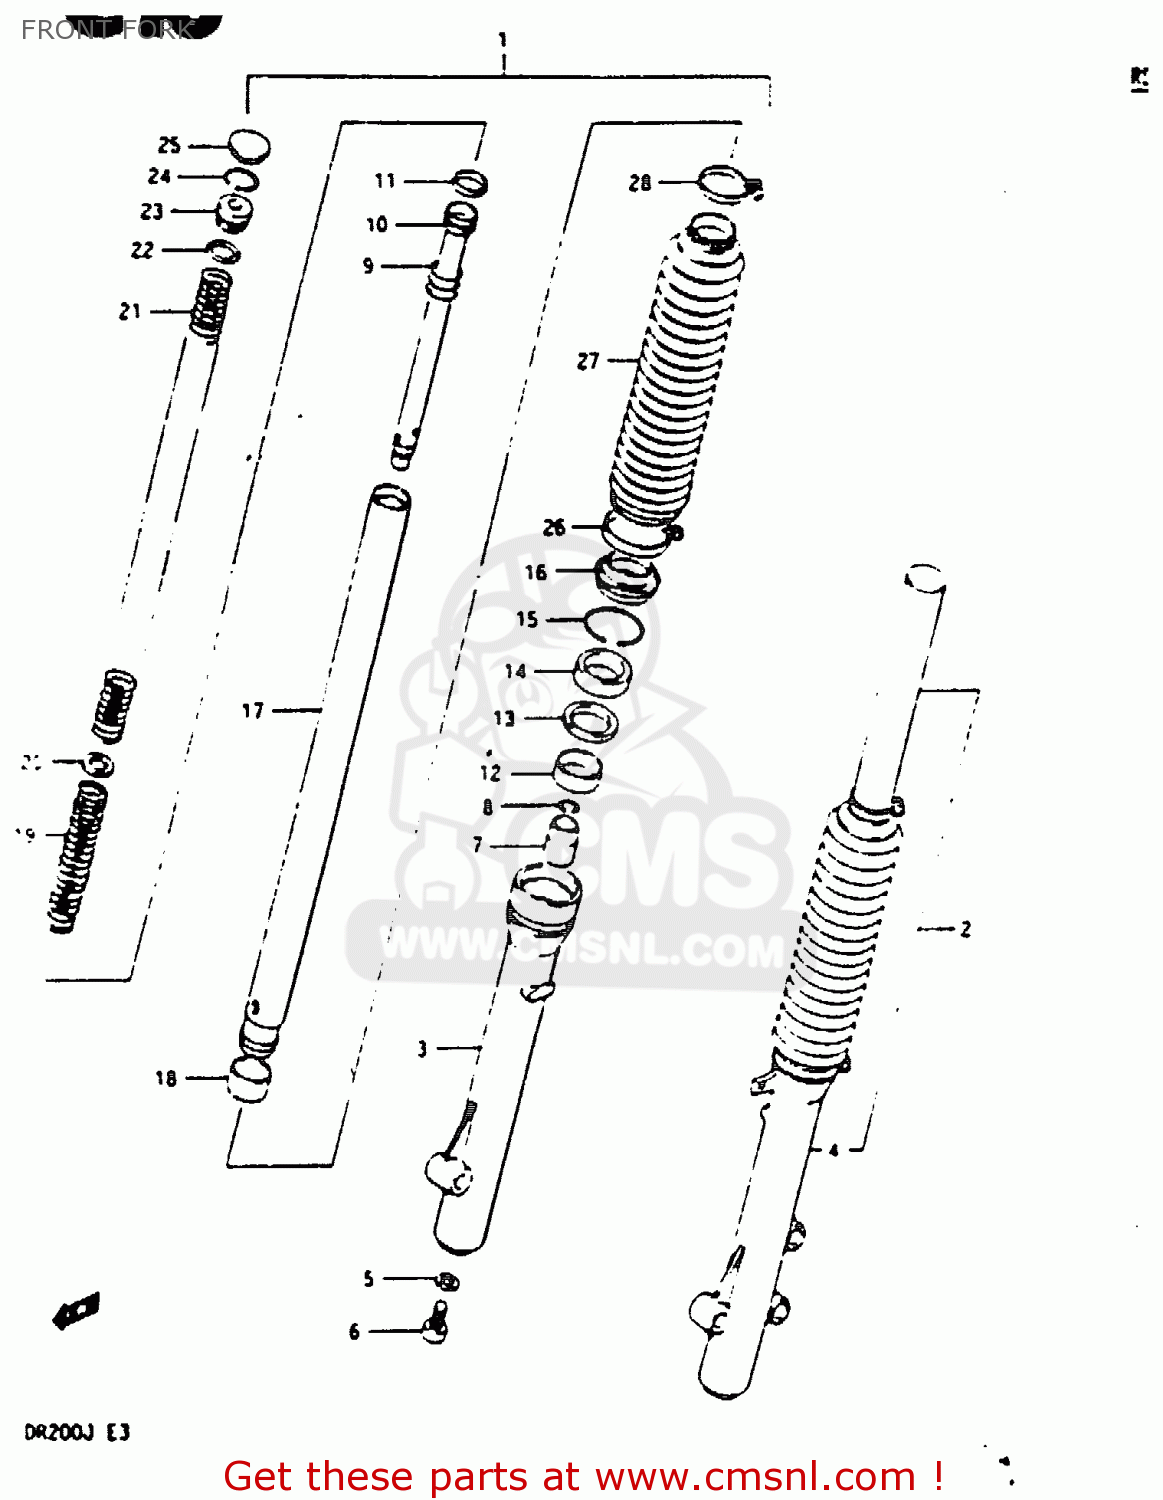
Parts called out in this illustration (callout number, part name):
1	DAMPER ASSEMBLY,RIGHT
2	DAMPER ASSEMBLY,LEFT
3	TUBE,OUTER,RIGHT
4	TUBE,OUTER,LEFT
5	GASKET (NAS)
6	BOLT(8X27)
7	PIECE,OIL LOCK
8	RING,STOPPER
9	SPRING,REBOUND
10	CYLINDER
11	RING,PISTON
12	BUSH,GUIDE
13	SPACER,SEAL
14	OIL SEAL,FRONT FORK
15	CIRCLIP,FORK OIL SEAL
16	SEAL,DUST
17	TUBE,INNER
18	PISTON
19	SPRING,LWR
20	SPRING,JOINT
21	SPRING,UPR
22	O RING
23	SEAT, SPRING
24	RING,STOPPER
25	CAP
26	BAND
27	BOOT
28	BAND
